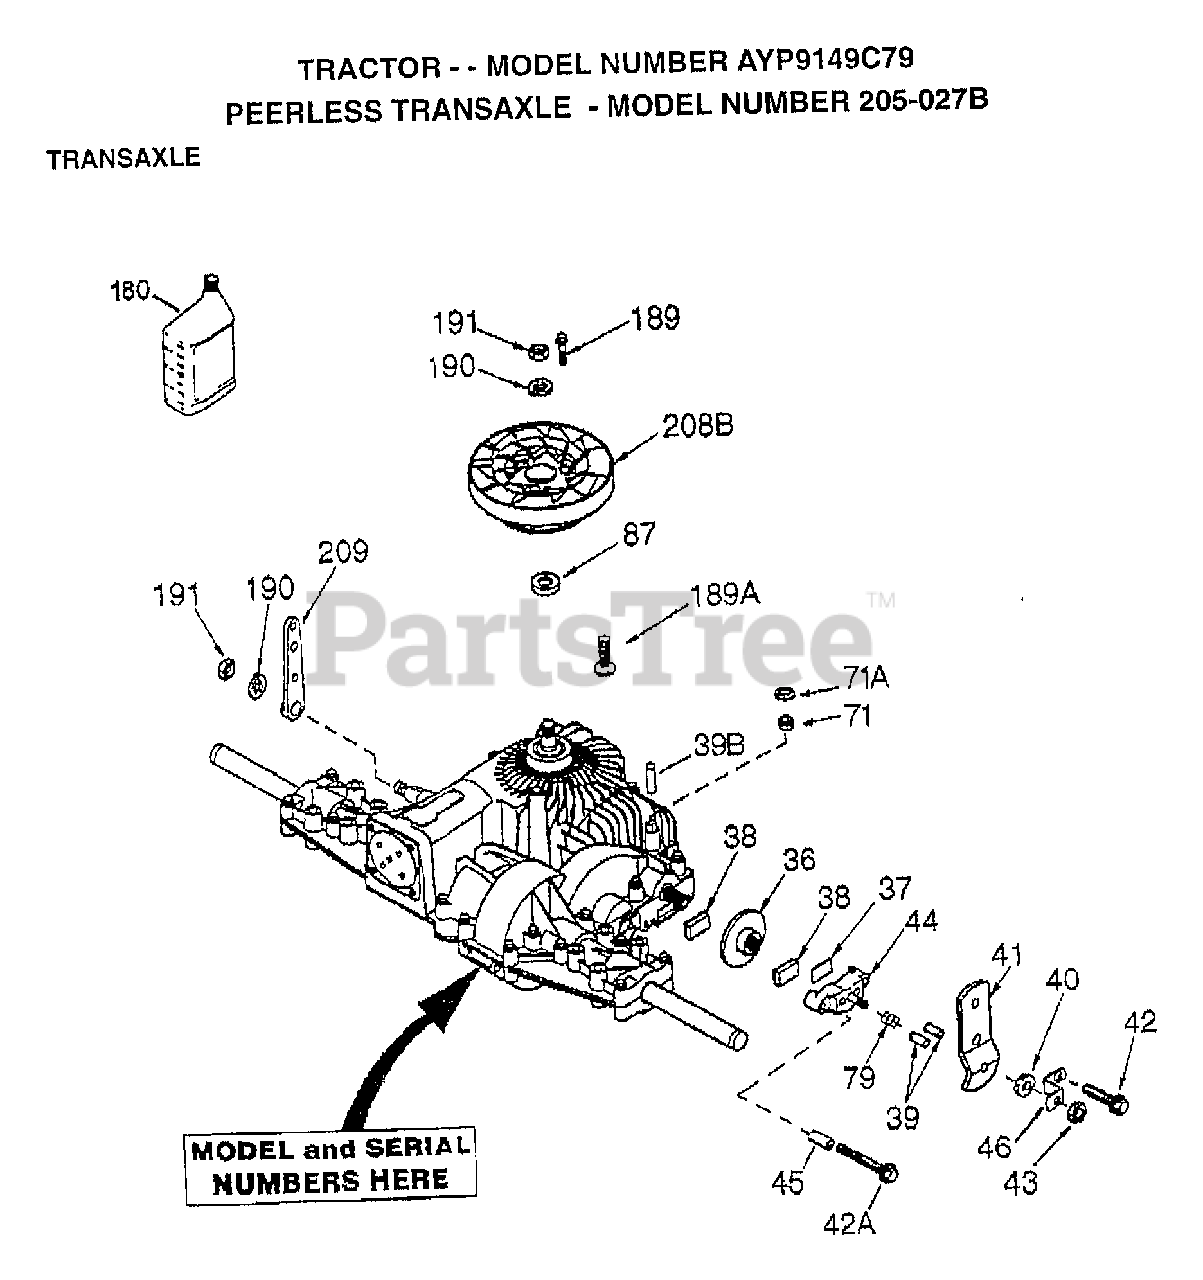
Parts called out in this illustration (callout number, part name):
37	PLATE BRAKE PAD
41	BRAKE LEVER
42	SCREW, 1/4-20 X 1-1/4
42A	SCREW, 1/4-20 X 2-1/4
43	LOCKNUT 5/16-24
44	HOLDER BRAKE PAD
46	BRAKE LEVER BRACKET
71	SEAL SQUARE CUT
180	GEAR OIL 80W90
189	DRIVE SCREW
208B	FAN/COUPLING
209	CONTROL LEVER
